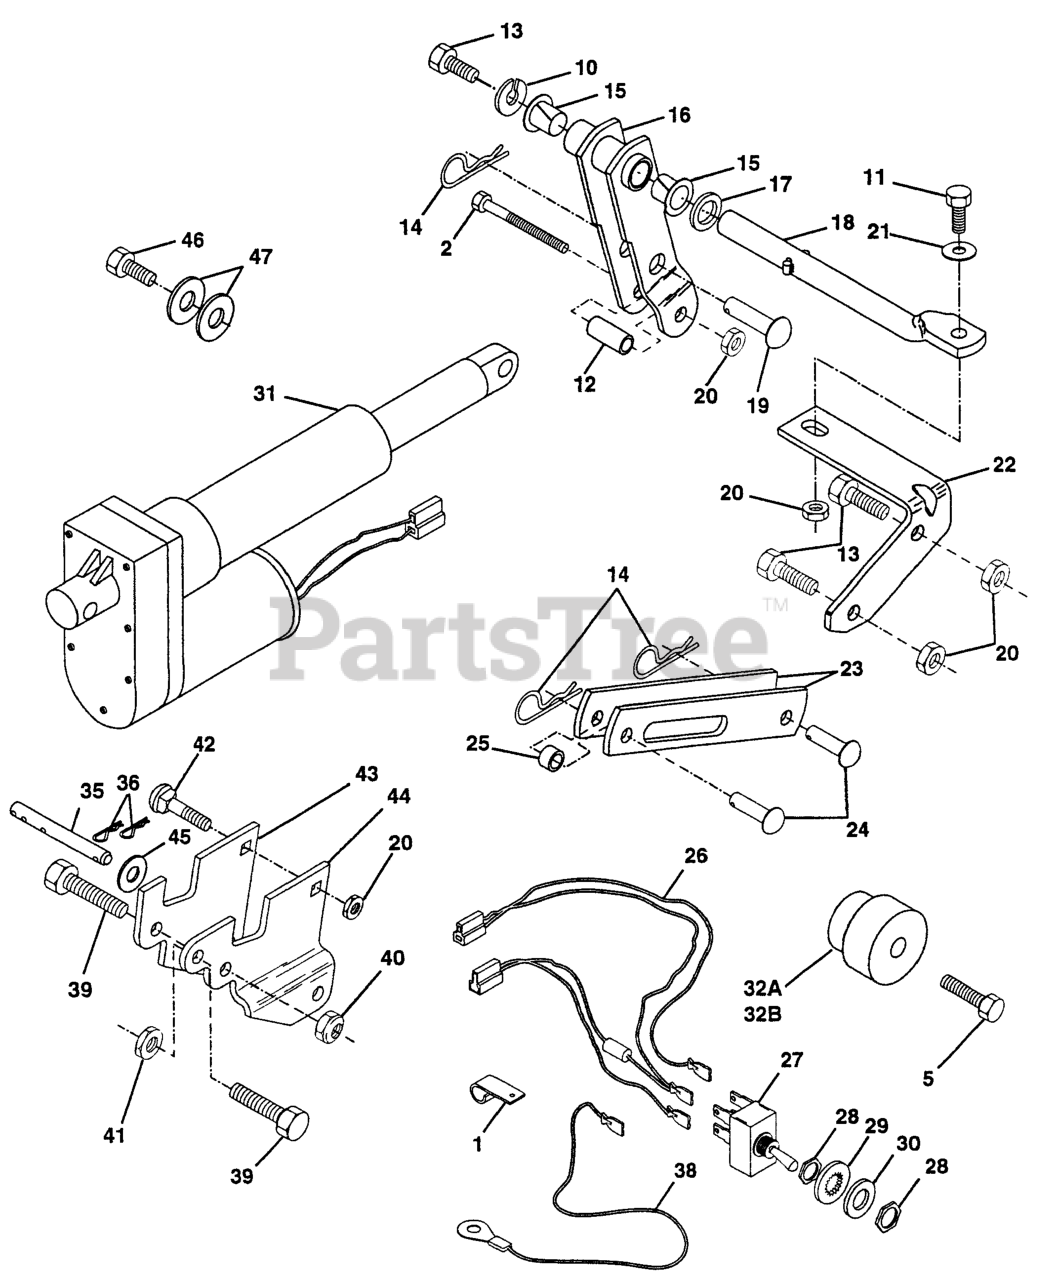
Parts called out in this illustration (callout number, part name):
1	Clip, Insulated
2	Bolt, Hex 3/8-16 x 2-1/4 Grade 5
5	Bolt, Hex 3/8-16 x 1-3/8
10	Washer, Lock
11	Bolt, Hex 3/8-16 x 1-1 /4
12	Bushing .384 x 1/2 x 1-1/4
13	Bolt, Hex 3/8-16 x 7/8
14	Spring, Retainer
16	Arm, Pivot
17	Washer 21/32 x 1 x 21 Ga.
18	Rod, Pivot Support
19	Pin, Pivot
20	Locknut 3/8-16
21	Washer 13/32 x 7/8 x 16 Ga.
22	Bracket, Pivot Rod
23	Link, Lift
24	Pin, Pivot
25	Spacer
26	Harness, Lift Kit
27	Switch, Lift
28	Nut, Switch
29	Washer, Lock Int. Tooth
30	Washer 15/32 x 3/4 x 16 Ga.
31	Electric, Actuator
32A	Hub, Lever Lift (Splined)
32B	Hub, Lever Lift (Tapered)
35	Pin, Actuator
36	Spring, Retainer
38	Wire, Ground
39	Bolt, Hex 7/16-14 x 1-1/4
40	Jam Nut 7/16-14
41	Locknut 7/16-14
42	Carraige Bolt 3/8-16 x 1-1/4
43	LH Actuator Bracket, Hydro
44	RH Actuator Bracket, Hydro
45	Washer 17/32 x 3/4 x 16 Ga.
46	Bolt, Hex 5/16-18 x 1-1/4
47	Washer 11/32 x 1-1/2 x 10 Ga.
